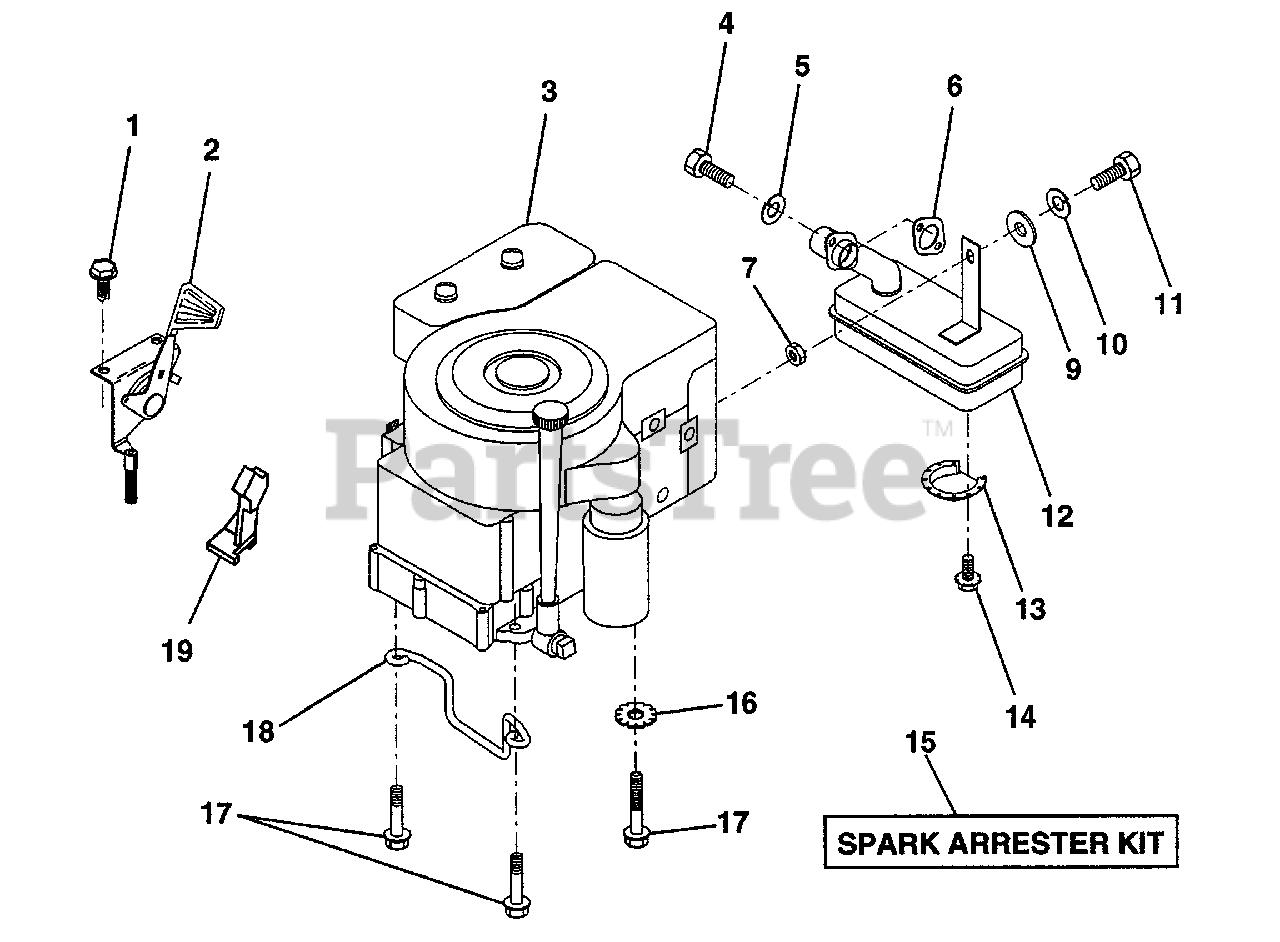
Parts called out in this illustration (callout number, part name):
1	Screw, Hex Thd. Cut 1/4-20 x 1/2
2	Control, Throttle
3	Engine,
4	Screw, Hex, Cap 5/16-18 x 3/4
5	Washer, Lock Heavy Helical Spring 5/16
6	Gasket, Exhaust
7	Nut, Hex 5/16-18
9	Washer 5/16 x 3/4 x 16
10	Washer, Lock Heavy Helical Spring 1/4
11	Bolt, Hex Fin. 1/4-20 UNC x 1-1/2
12	Muffler
13	Deflector, Muffler
14	Screw, Spiderlock Hex Hd. 8 x 1 /2 ABTPS
15	Arrester, Spark
16	Lock, Water Ext. Tooth 3/8
17	Screw, Hex Wsh Hd Thdrol 3/8-1 6 x 1-1/2
18	Keeper, Ground Drive Belt
19	Stop, Throttle
